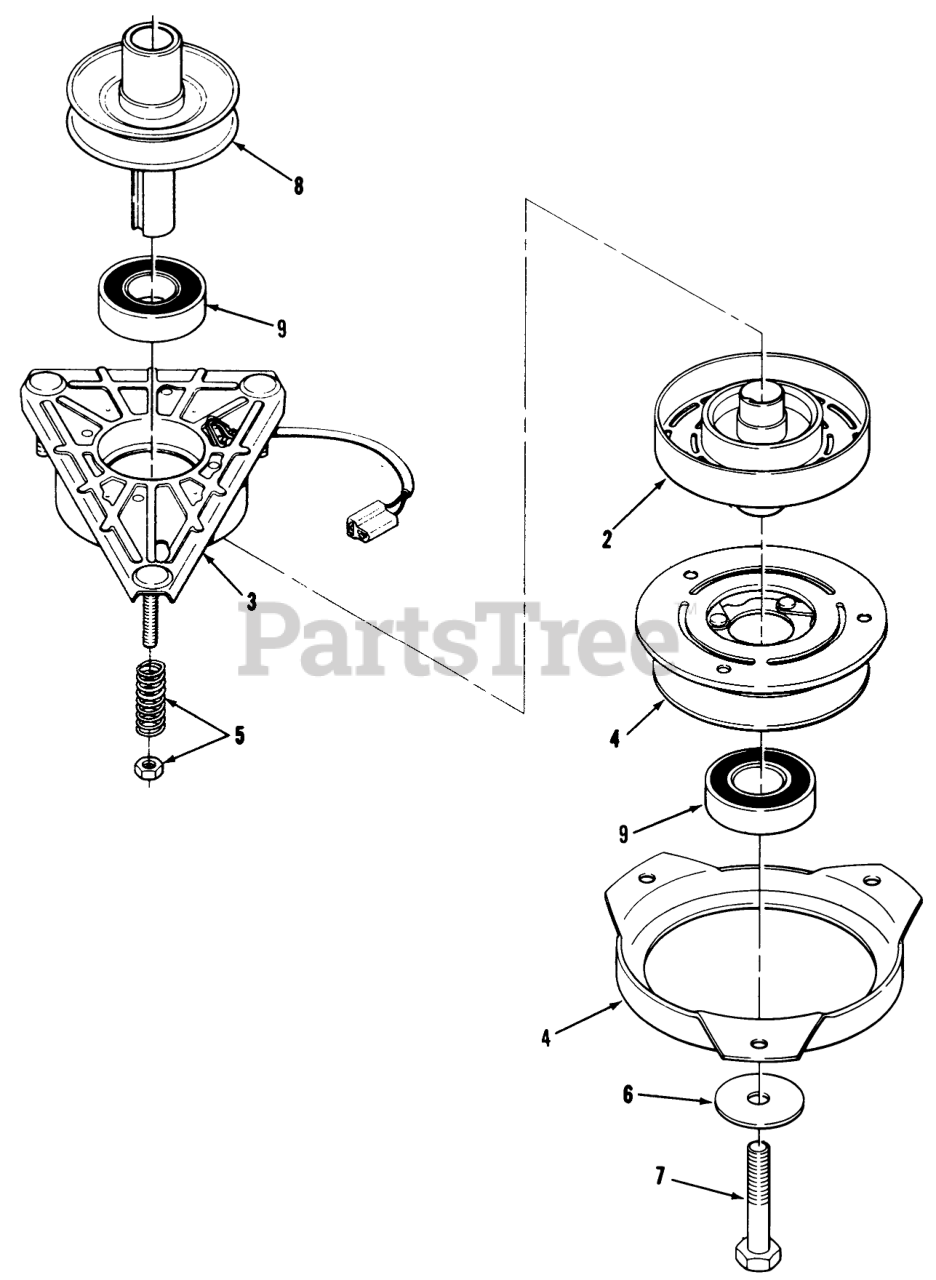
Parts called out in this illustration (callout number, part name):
1	Electric Clutch Assembly (Includes items 2, 3, 4, & 5)
2	Rotor Assy
3	Field Assembly (Includes one of item 9)
4	Armature and Pulley Assembly (Includes one of item 9 and Brake Plate)
5	ACCESS SPRING & NUT
6	WASHER
7	HHCS M10X1.5X120
8	PULLEY-ENGINE
9	BEARING-ELEC CLUTCH
